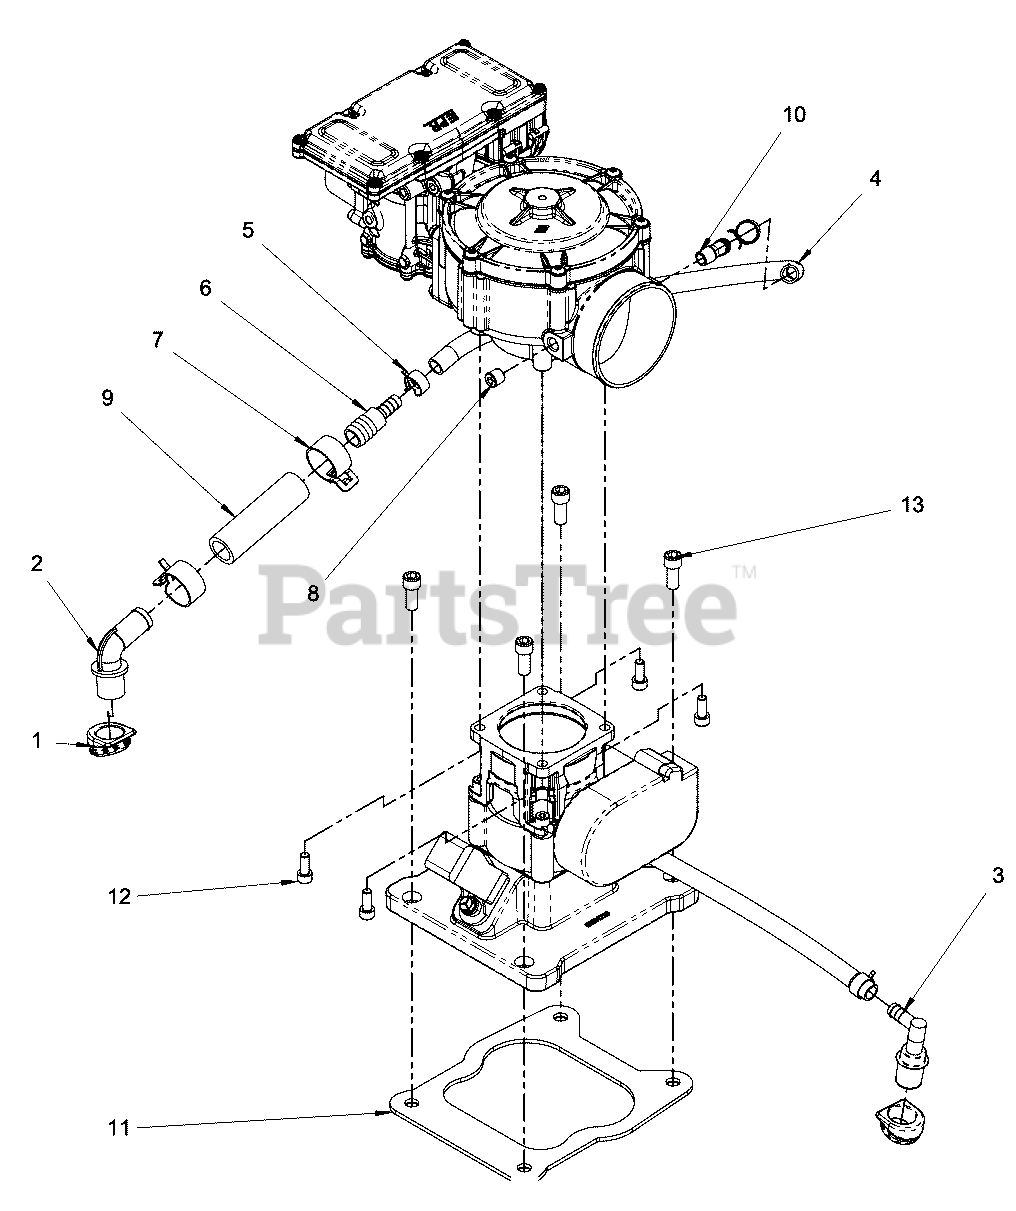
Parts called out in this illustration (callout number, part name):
8	* PLUG
10	* FITTING
12	* BOLT
13	* BOLT
